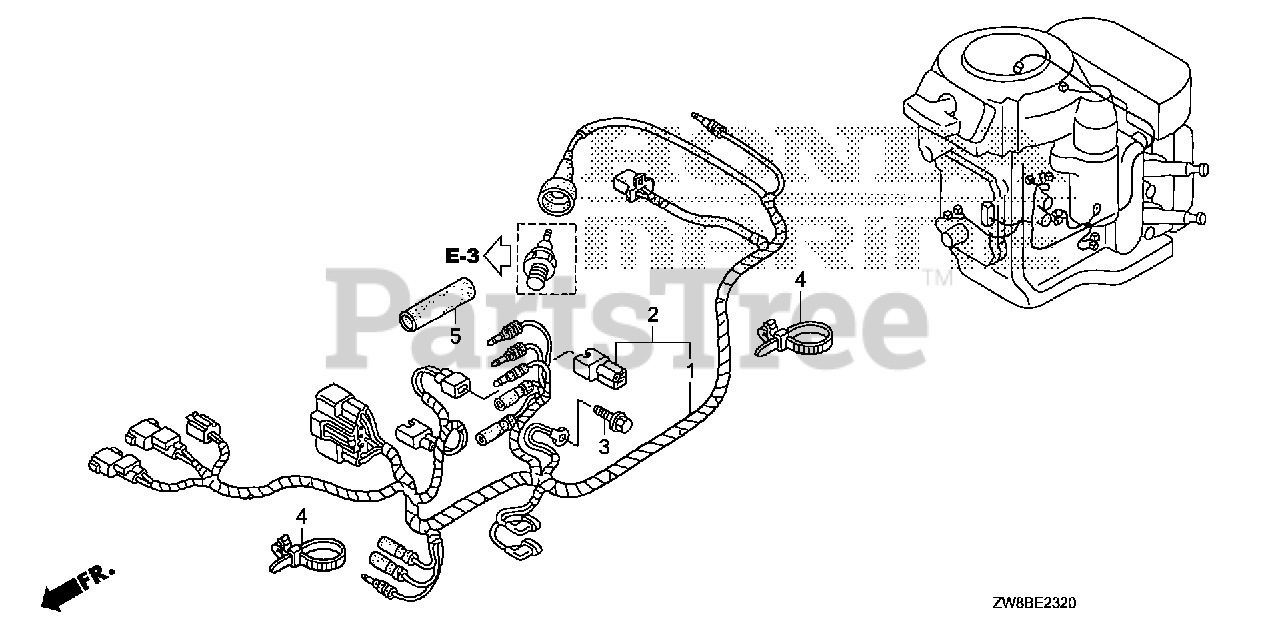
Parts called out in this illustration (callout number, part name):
2	WIRE HARNESS ASSY.
3	BOLT, FLANGE (6X12)
4	BAND, WIRE (95MM)
5	TUBE, RUBBER (11.5X14.5)
